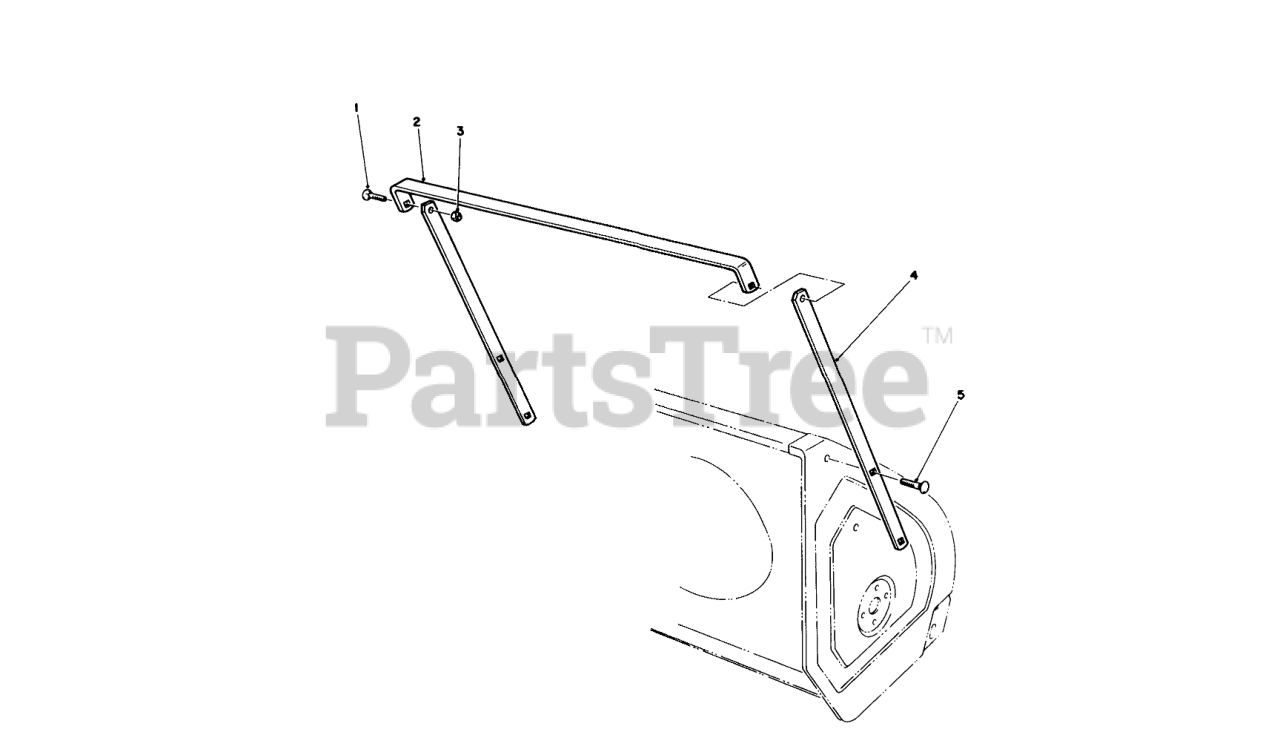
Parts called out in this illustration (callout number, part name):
1	SCREW-CARR
3	NUT-LOCK, NI
4	Breaker-Side
5	BOLT-CARR
